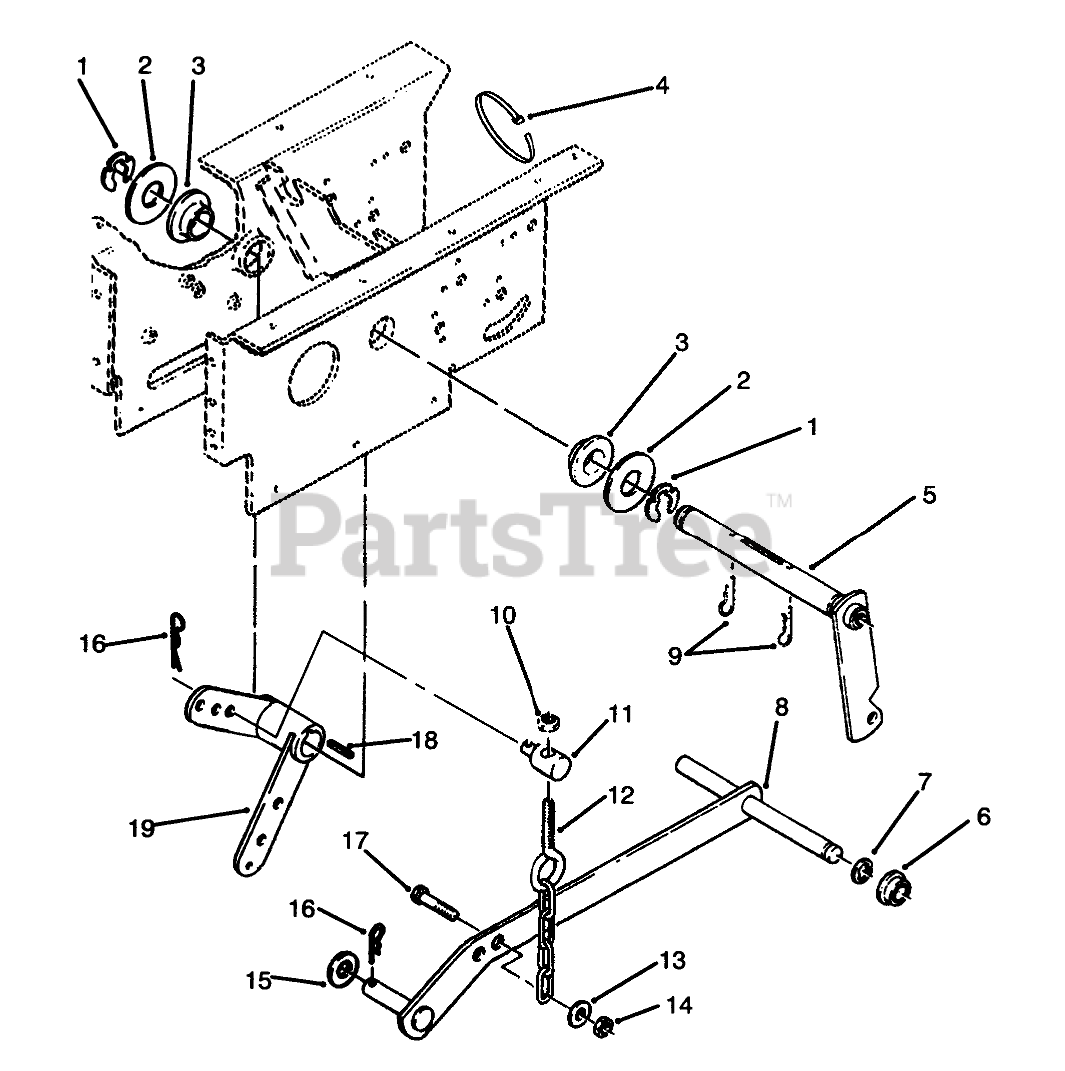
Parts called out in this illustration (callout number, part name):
1	RING-RETAINING
2	WASHER-FLAT
3	BEARING-FLANGE
4	TIE-CABLE
5	WLDMT-LIFT ARM
6	BUSHING
7	RING-RETAINING, EXTERNAL
8	Bar-Lift
9	Pin-Cotter
10	NUT-LOCK, NI
11	TRUNNION-LIFT
12	CHAIN-LIFT
13	WASHER-PLAIN
14	NUT-LOCK, NI
15	WASHER-FLAT
16	Hairpin Cotter
17	SCREW-HH
18	KEY-SQUARE
19	LIFT LEVER ASM
